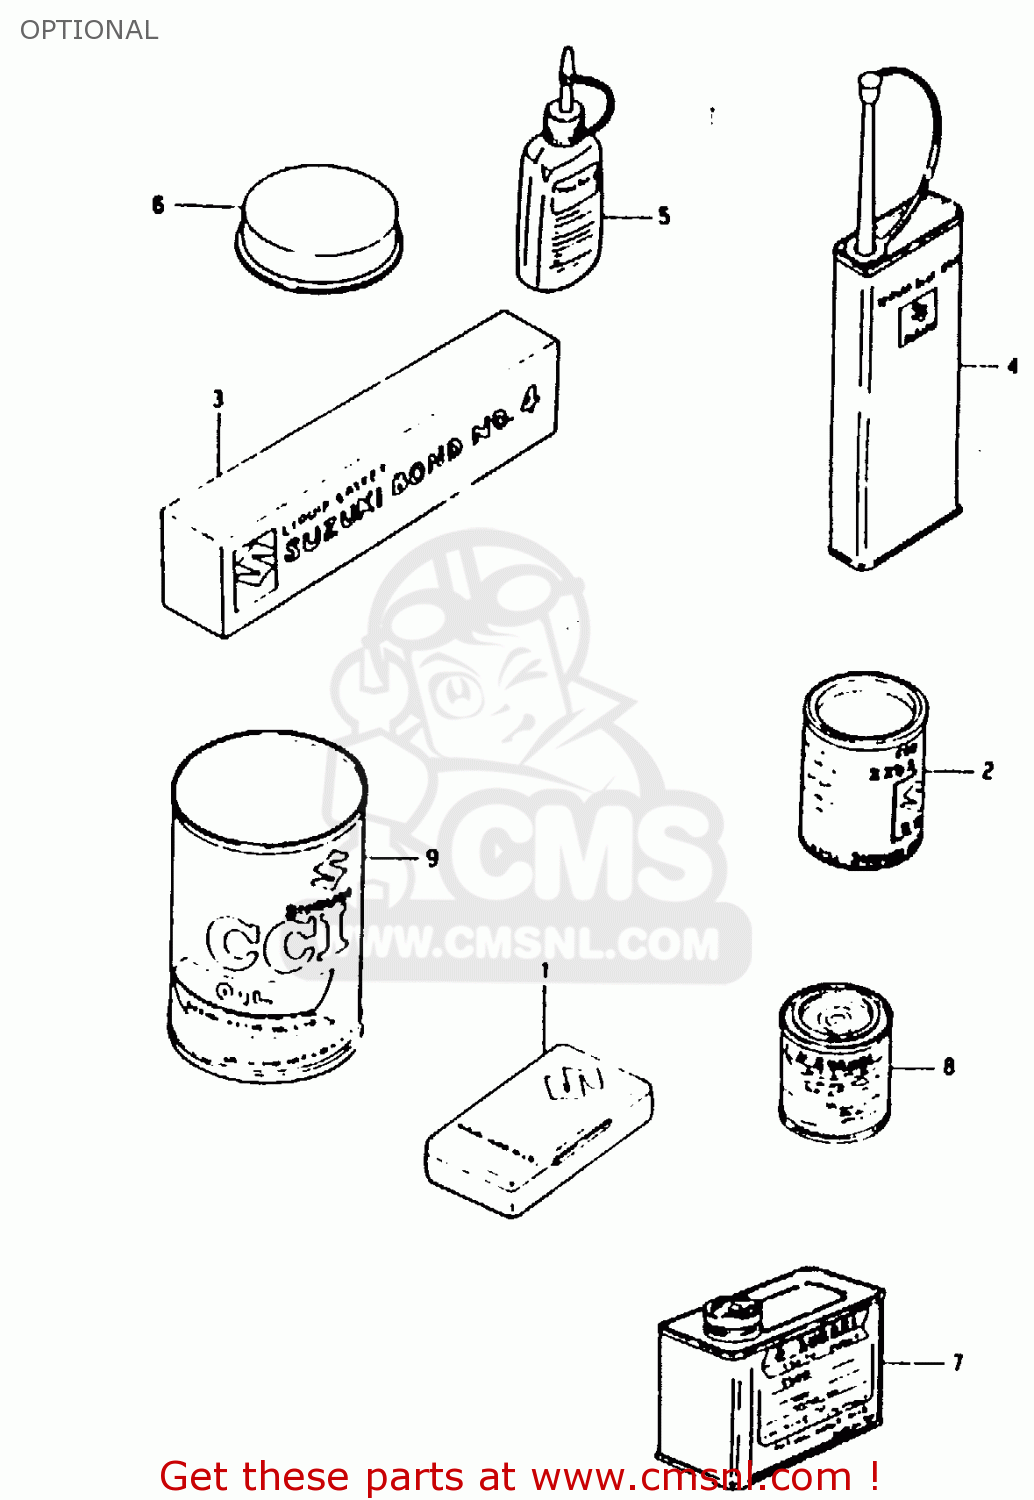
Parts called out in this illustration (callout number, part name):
1	TUBE REPARING TOOL
2	GREASE(C)EP2 LITHIUM 150G
3	BOND 1104
4	THREAD LOCK NO.1401 CLEAR 200G
5	THREAD LOCK NO
6	GREASE,PBC FOR BRK PAD 20G
7	PAINT (BLACK)
8	PAINT,BLACK
9	CCI OIL
